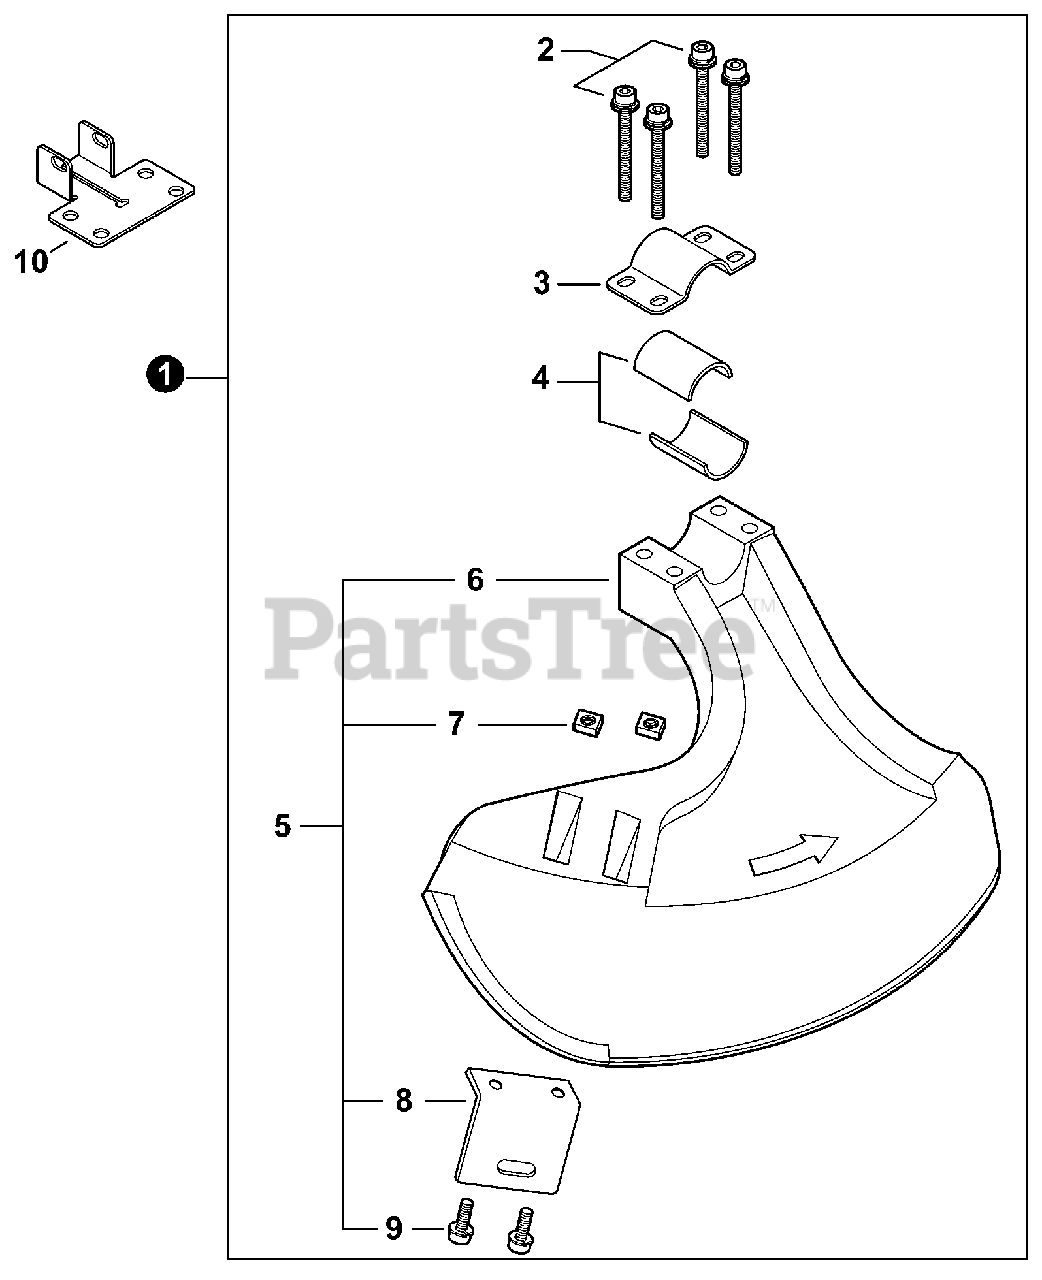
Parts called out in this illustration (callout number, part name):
1	DEBRIS SHIELD KIT
2	BOLT M5×45
3	CLAMP, UPPER
4	SPACER 24
5	DEBRIS SHIELD ASSY
6	SHIELD, DEBRIS
9	BOLT M5×16
10	PLATE, SHIELD MOUNTING
